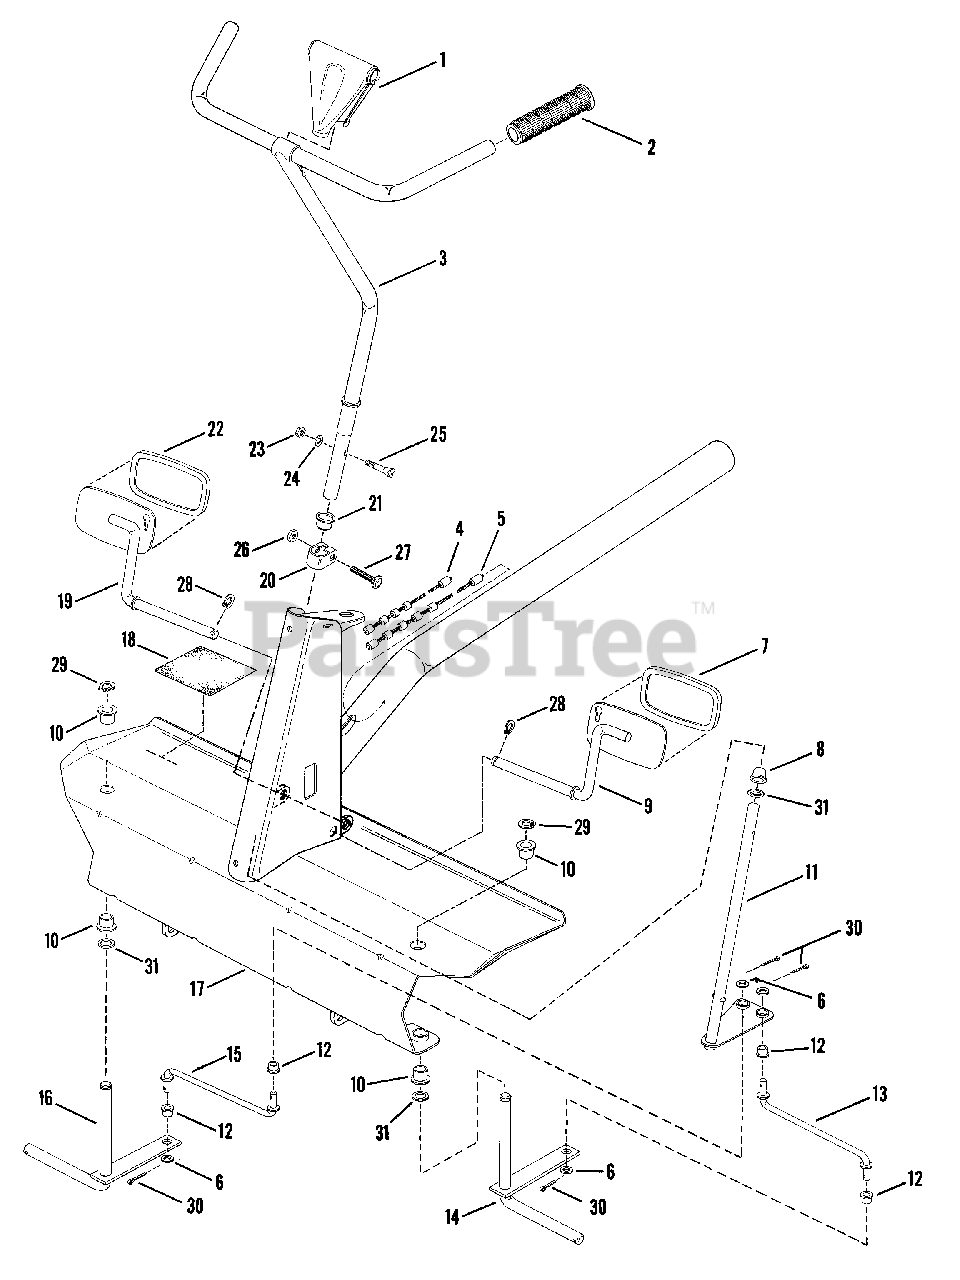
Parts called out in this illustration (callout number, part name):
1	COVER, Handle
2	GRIP, Handle
3	HANDLE, Steering
4	CABLE, Auxiliary Brake
5	CABLE, Clutch/Brake
6	WASHER, 3/8 SAE
7	PAD, Clutch/Brake Pedal
8	BUSHING, Nylon
9	PEDAL, Clutch/Brake, Left Hand
10	BEARING
11	SHAFT, Steering
12	BUSHING, Tie-Rod
13	TIE-ROD, Left Hand
14	King Pin, L.H.
15	TIE-ROD, Right Hand
16	King Pin, R.H.
17	FRONT AXLE STRUCTURE
18	PAD, Foot
19	PEDAL, Auxiliary Brake, Right Hand
20	CLAMP, Steering
21	BUSHING, Nylon
22	PAD, Auxiliary Brake Pedal
23	NUT, 1/4-28 Hex
24	LOCKWASHER, 1/4" Internal Tooth
25	BOLT, 1/4-28 Tapered Head
26	NUT, 5/16-18 Hex
27	BOLT, 5/16-18 x 1-1/2" Carriage
28	RING, 1/2" External Retaining
29	RING, 3/4" External Retaining
30	PIN, 1/8 x 3/4" Cotter
31	WASHER, 3/4" I.D. x 1-1/8" O.D. Flat
